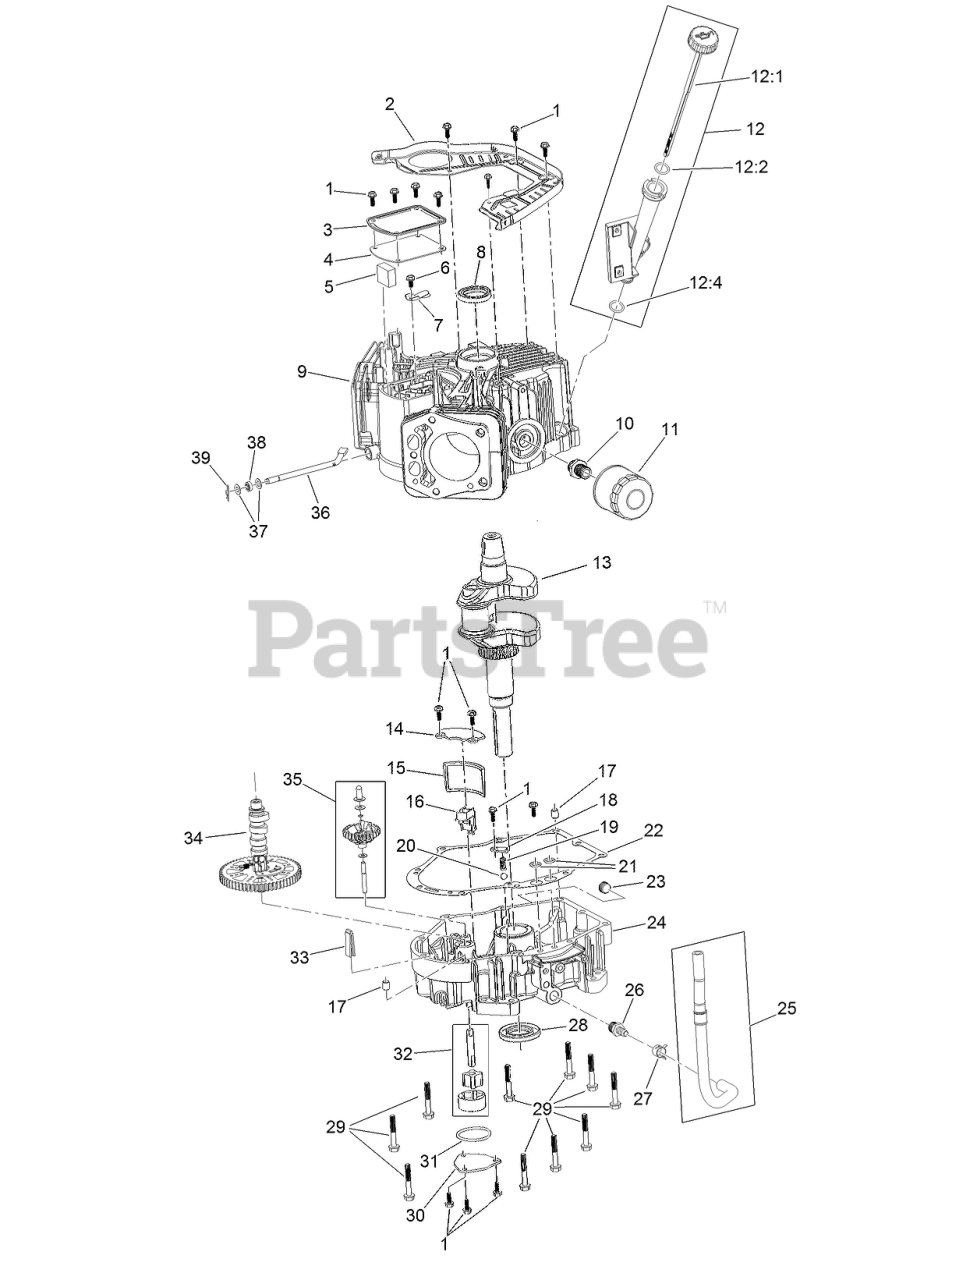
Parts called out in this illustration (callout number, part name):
1	SCREW-HHF
2	BAFFLE
3	COVER-BREATHER
4	GASKET-BREATHER
5	FILTER-BREATHER
6	SCREW-HHF
7	VALVE-BREATHER
8	SEAL-OIL
9	CRANKCASE
10	FITTING-THREADED, OIL FILTER
11	FILTER-OIL
12	OIL TUBE ASM
12:1	DIPSTICK
12:2	O-RING
12:4	O-RING
13	CRANKSHAFT
14	COVER-SCREEN, OIL
15	SCREEN-OIL
16	RETAINER-SCREEN
17	PIN-DOWEL
18	PLATE-RETAINER
19	SPRING
20	VALVE-BALL
21	O-RING
22	GASKET-COVER, CRANKCASE
23	PLUG-DRAIN
24	COVER-CRANKCASE
25	OIL DRAIN HOSE ASM
26	FITTING-HOSE
27	CLAMP-HOSE
29	SCREW-HHF
30	COVER-OIL PUMP
31	O-RING
32	OIL PUMP ASM
33	DEFLECTOR-OIL, RUBBER
34	CAMSHAFT
35	GOVERNOR ASM
36	ROD-GOVERNOR
37	WASHER-PLAIN
38	SEAL-OIL
39	PIN-HAIR
